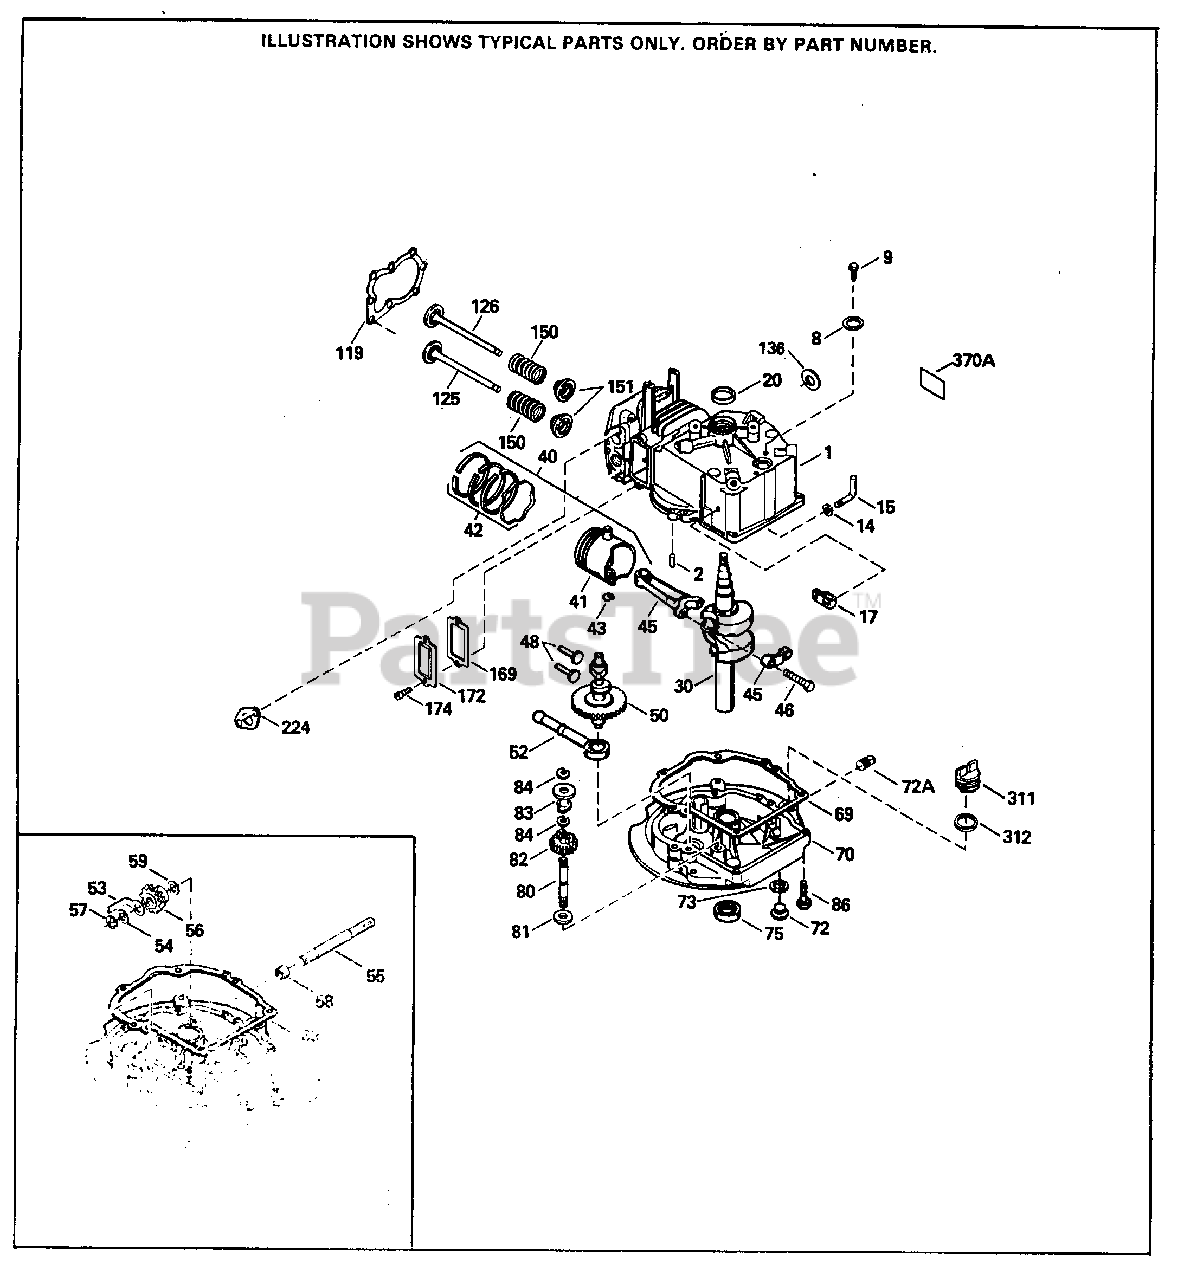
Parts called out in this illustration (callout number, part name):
1	"Cylinder (Incl. 2,8,9,20 & 136) 2-1/2 " Bore
2	Dowel Pin
8	Breather Gasket
9	Screw, 10-24 x 9/16"
14	Flat Washer
15	Governor Rod
17	Governor Lever clamp
20	Oil Seal
30	Crankshaft
40	Piston, Pin & Ring Set (.010" OS)
40	Piston, Pin & Ring Set (.020" OS)
40	Piston, Pin & Ring Set (Std.) 2-1/2"B ore
41	Piston & Pin Ass'y. (Std.) (Incl. 43) (2-1/2")
41	Piston & Pin Ass'y. (.010" OS) Incl. 43
41	Piston & Pin Ass'y. (.020" OS) Incl. 43
42	Ring Set (Std.)
42	Ring Set (.010" OS)
42	Ring Set (.020" OS)
43	Piston Pin Retaining Ring
45	Connecting Rod (Incl. 46)
46	Connecting Rod Bolt
48	Valve Lifter
50	Camshaft (MCR)
52	Oil Pump Ass'y.
69	Mounting Flange Gasket
70	Mounting Flange Incl. 72, 73, 75 & 80
72	Drain Plug (Incl. 73)
72A	Oil Drain Plug
73	Drain Plug Gasket
75	Oil Seal
80	Governor Shaft
82	Governor Gear
83	Governor Spool
84	Retaining Ring
86	Screw, 1/4-20 x 1-1/4"
119	Cylinder Head Gasket
125	Exhaust Valve (Std.) (Incl. 151)
125	Exhaust Valve (1/32" OS) (Incl. 151)
126	Intake Valve (Std.) (Incl. 151)
126	Exhaust Valve (1/32" OS) (Incl. 151)
136	S.E. Brake Washer
150	Valve Spring
151	Valve Spring Cap
169	Valve Cover Gasket
172	Valve Spring Cover
174	Screw, 10-24 x 1/2"
224	Intake Gasket
370A	Lubrication Decal
